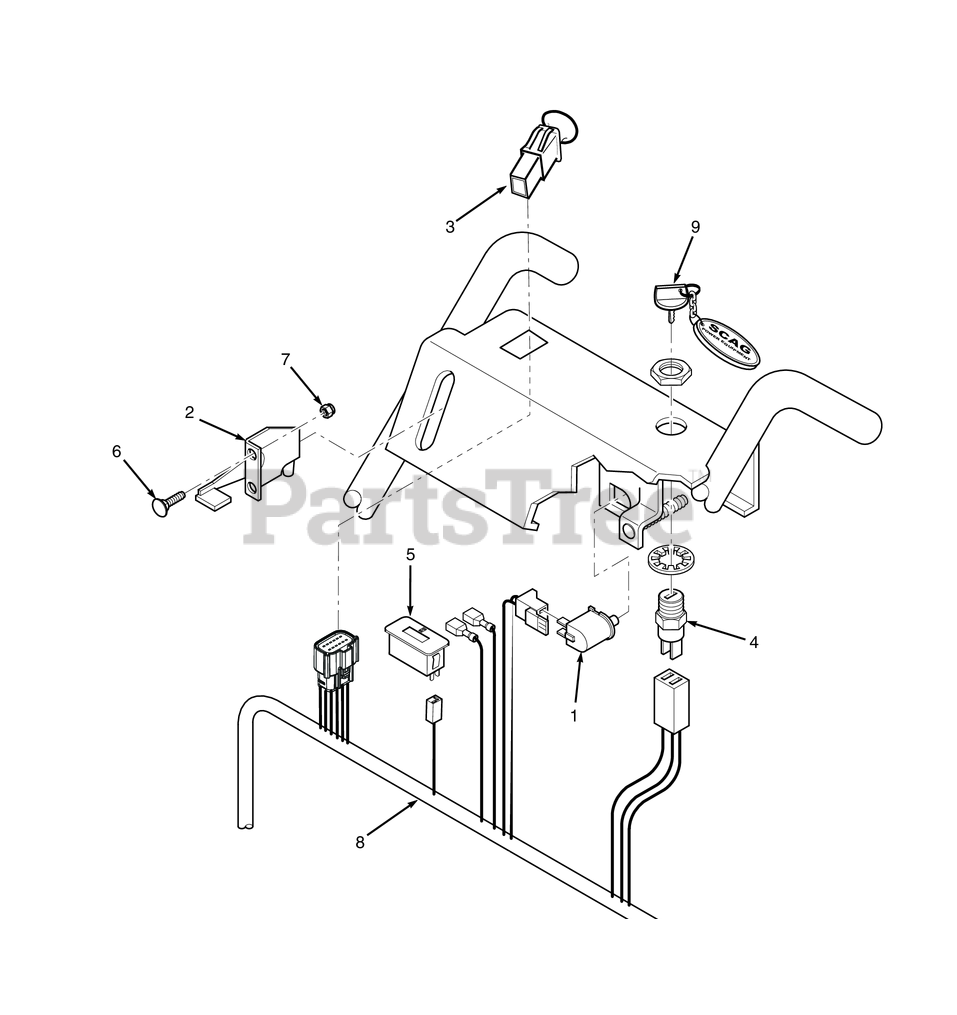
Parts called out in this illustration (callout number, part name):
1	SWITCH, NEUTRAL INTERLOCK
2	Throttle Control (15KA & 17KA)
3	Switch, PTO - 10 Amp
4	KEY SWITCH, MANUAL SRT.(INCL. HWD)
5	Hour Meter, Inductive
6	Bolt, Carriage #10-24 x 1/2"
7	Nut, Elastic Stop #10-24
8	Handle Wire Harness, Manual Start
9	Key, Assembly w/Fob
NS	Clamp, Cable 1/2" I.D.
